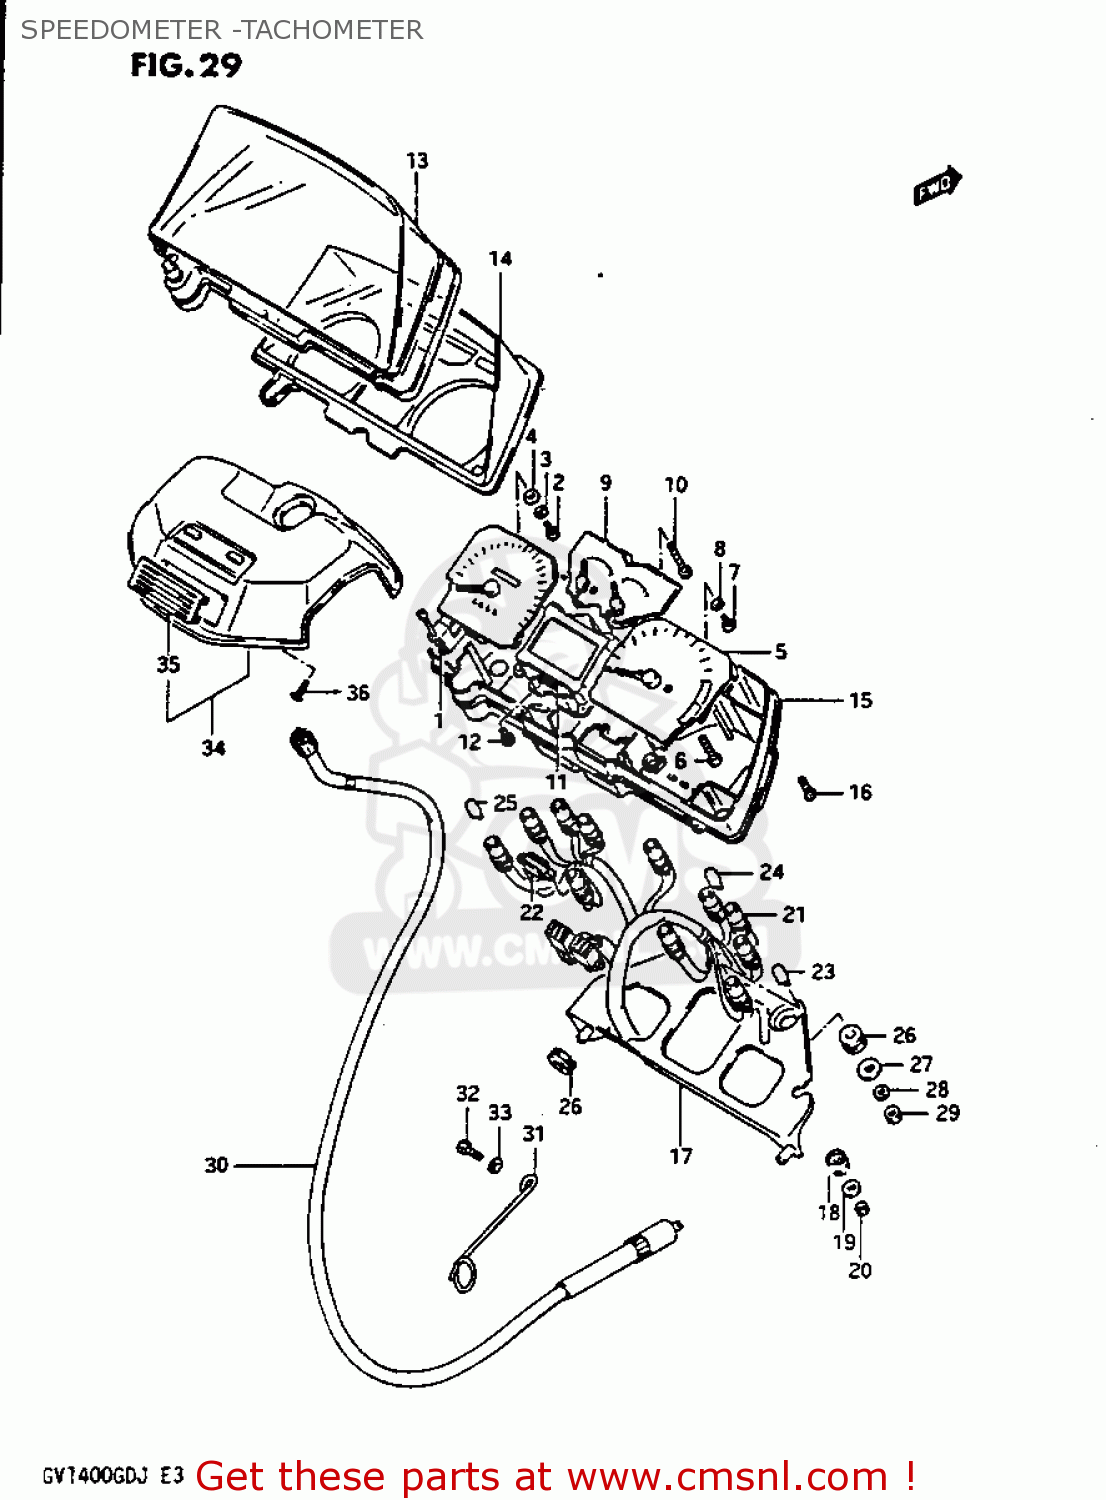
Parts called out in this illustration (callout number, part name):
1	METER,SPEEDOMETER (KM/MPH)
2	SCREWM4X0.7X10
3	LOCK WASHER
4	WASHER
5	METER,TACHOMETER
6	SCREW
7	SCREW
8	LOCK WASHER
9	FUEL & TEMP METER
10	SCREW(3X22)
11	UNIT,INDICATOR
12	SCREW
13	HOOD,METER
14	PANEL,METER
15	CASE,METER
16	SCREW,L:12
17	BRACKET,METER
18	CUSHION
19	WASHER (5.5X16X1.2)
20	NUT
21	SOCKET,METER
22	LEAD SWITCH
23	BULB(12V3.4W,T10)
24	BULB(12V1.7W,T10,WB121)
25	BULB 12V 1.7W
26	CUSHION
27	WASHER(6.5X20X1.6)
28	WASHER,LOCK
29	NUT
30	CABLE ASSY,SPEEDOMETER
31	CLAMP,SPEEDOMETER CABLE
32	BOLT
33	WASHER
34	SWITCH ASSEMBLY,TIME ADJUST
35	LOUVER
36	SCREW
